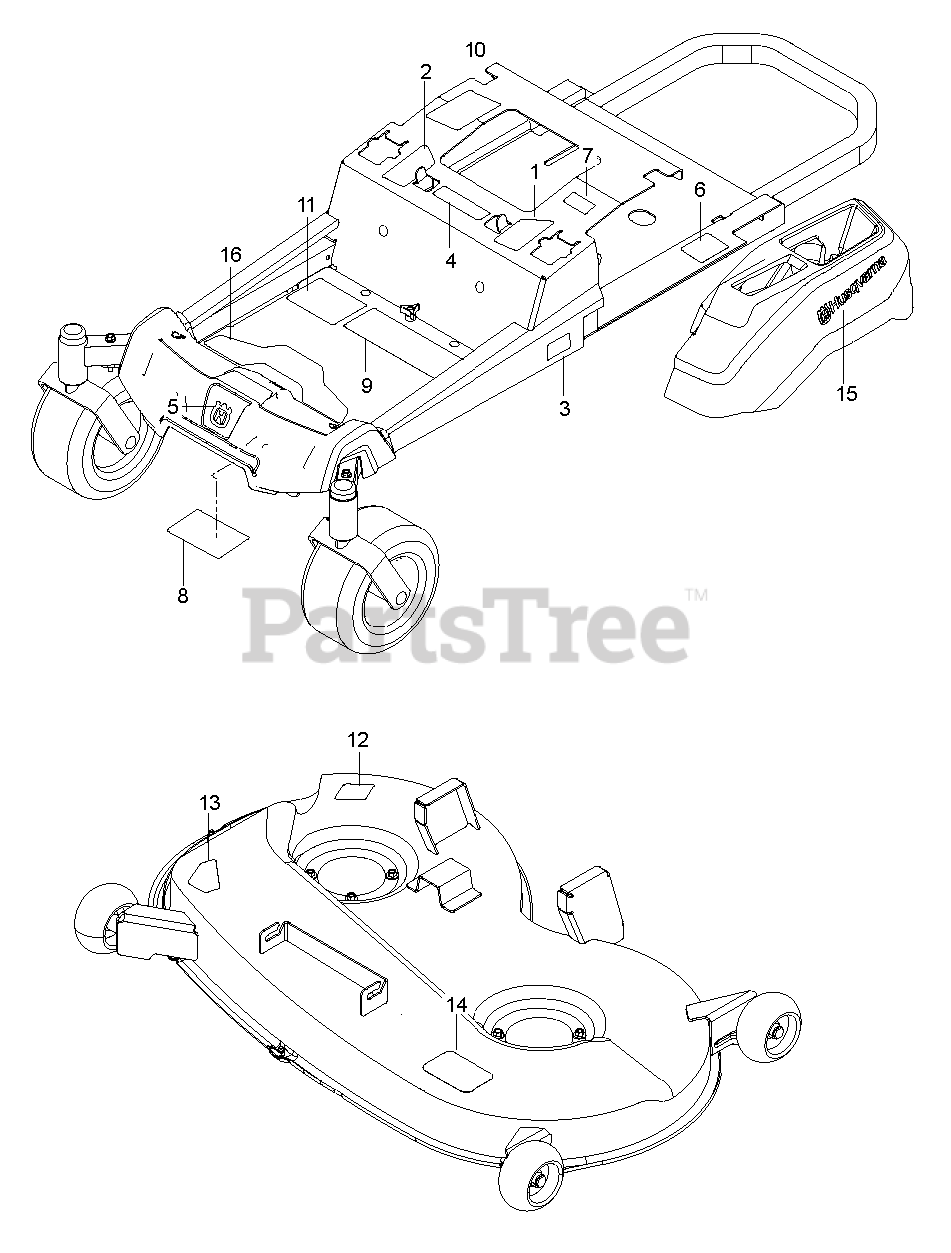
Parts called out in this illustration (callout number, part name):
1	DECAL.ZTR.RZ.THRTL/PRKBRK.V2.L
2	DECAL.ZTR.RZ.THRTL/PRKBRK.V2.R
3	DECAL.ZTR.SIDERAIL.Z246I.HU
4	EURO DECAL-BATTERY WARNIN6
5	DECAL.BADGE.55MM.CROWNH.HUSQ
6	DECAL, DO NOT TOW
7	DECAL, EXITING MOWER
8	DECAL, SERVICE
9	DECAL.ZTR.WARNING.SMARTIGNITIN
10	DECAL.WARNING.CUST.RESP.E85.
11	DECAL.STARTINGINSTRUC.SIS.ZTR
12	DECAL.DECK.6MIL./DEF.SHLD.WARN
13	DECAL, DECK DEFLECTOR, WARNING
14	DECAL, BELT ROUTING
15	DECAL.HUSQVARNA.210MM
16	PAD.RZ.FOOTREST.PLATE
